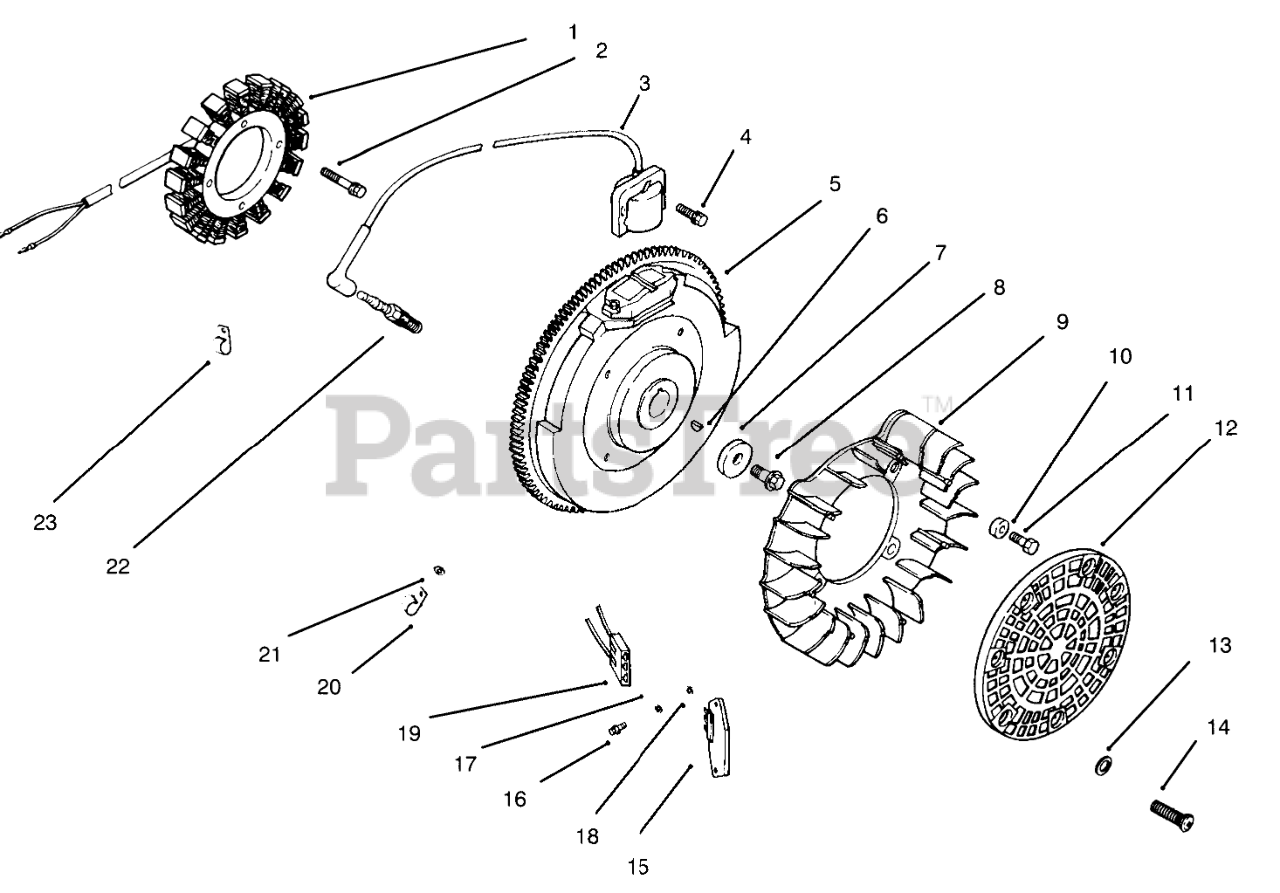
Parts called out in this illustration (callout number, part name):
1	Stator-15 amp
2	Screw
3	Module-Ignition
4	Screw
5	Flywheel Assembly
6	Key
8	Screw
10	Spacer-Fan
11	Screw
12	Screen-Grass
13	Washer
15	Rectifier-Regulator
17	Washer
18	Washer
19	Connector
20	Clip
21	Washer
22	Spark Plug
